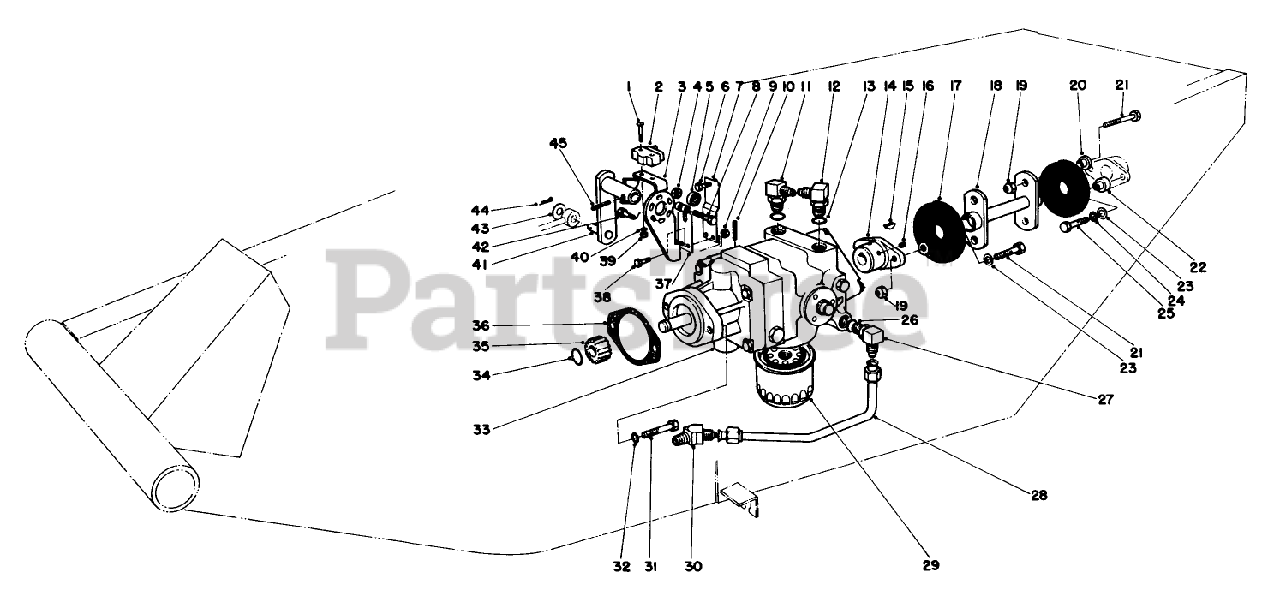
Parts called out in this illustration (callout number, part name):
1	SCREW-MACHINE
2	Micro Switch
3	Plate-Pump
4	NUT-LOCK, NI
5	BEARING-BALL
6	SCREW-HH
7	EXTENDED LEAF SPRING ASM
8	SCREW-HH
9	NUT-LOCK, NI
10	PIN-ROLL, SLOTTED
11	FITTING-HYD, 90 DEG
12	FITTING-ELBOW, 90 DEG
13	0-Ring
14	HUB-PUMP
15	KEY-WOODRUFF
16	SCREW-SET, HSH
17	Coupling Rubber
18	Drive Coupling
19	NUT-LOCK, CONE
20	SPACER-COUPLING
21	SCREW-HH
22	SPACER-COUPLING, RUBBER
23	WASHER-FLAT
24	Lockwasher
25	SCREW-HH
26	O-RING
27	FITTING-ELBOW, 90 DEG
28	AXLE-PUMP TUBE ASM
29	FILTER-OIL, TRANSMISSION
30	45 DEG FITTING
31	SCREW-HH
32	WASHER-LOCK
33	Transmission-Inline
34	Ring-Snap
35	Gear
36	GASKET
37	SPRING-LEAF
38	SCREW-HH
39	NUT-HEX
40	WASHER-LOCK, INTERNAL
41	Lever-Pump
42	1/4-20 X 3/4 THDG SCR
43	WASHER-FLAT
44	PIN-COTTER
45	PIN-SPRING
